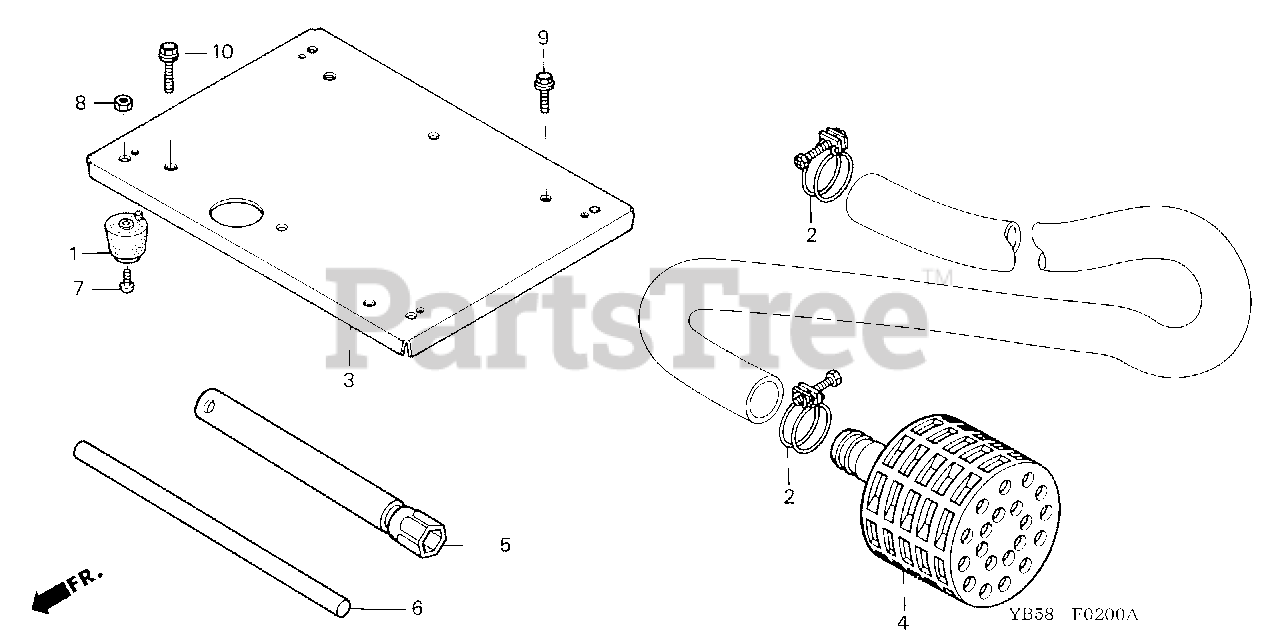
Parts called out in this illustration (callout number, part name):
1	RUBBER (LOWER)
2	BAND, HOSE
3	BED, FRAME
4	STRAINER
5	WRENCH, SPARK PLUG
6	HANDLE, BOX WRENCH
7	SCREW, PAN (6X10)
8	NUT, HEX. (6MM)
9	BOLT, FLANGE (8X25)
10	BOLT, FLANGE (8X28)
